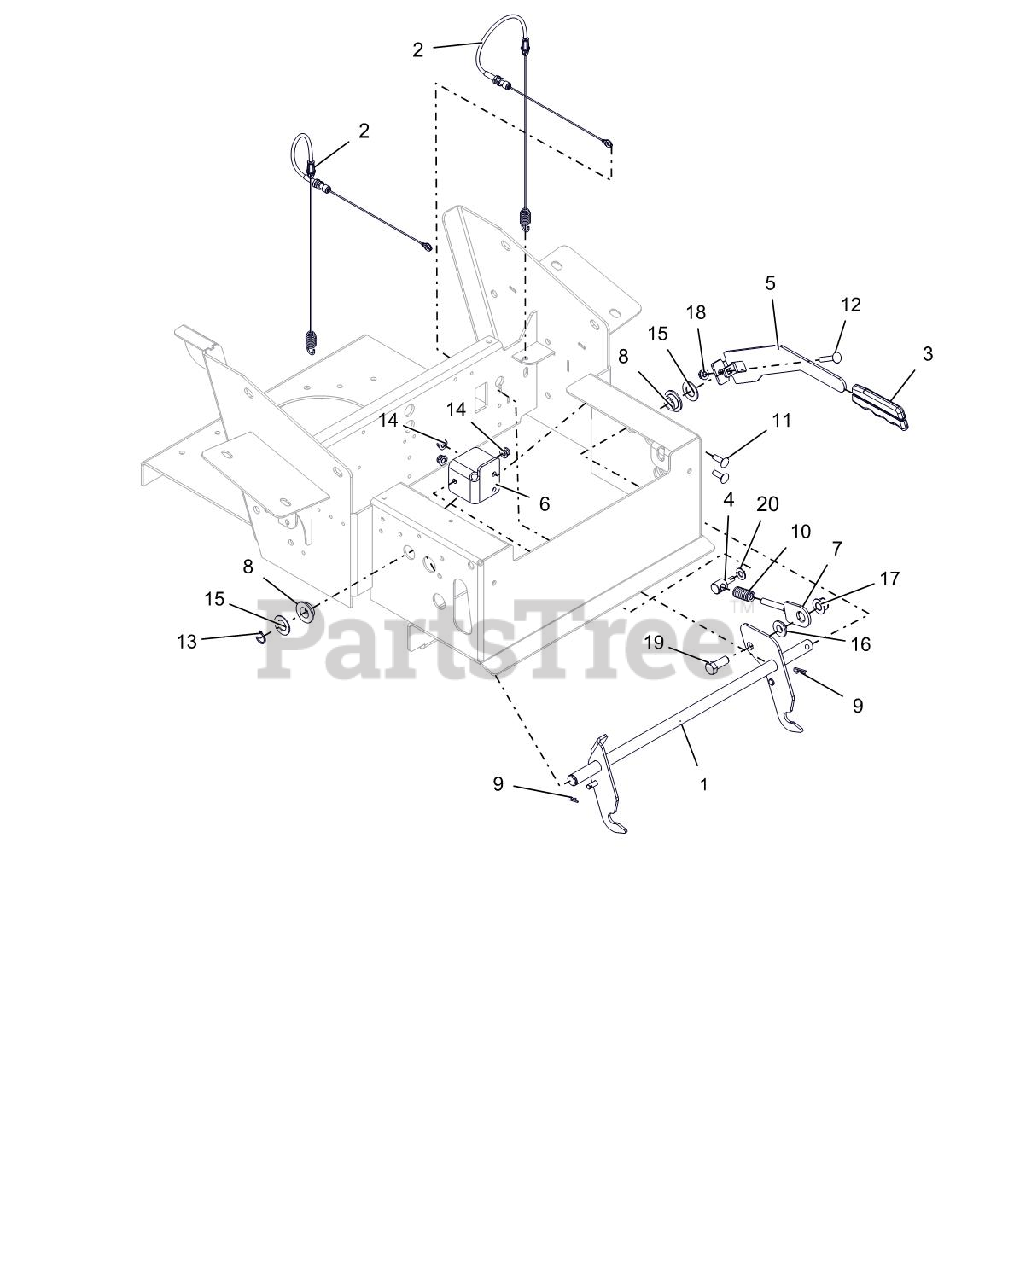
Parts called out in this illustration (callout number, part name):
1	PT/PT100 BRAKE LEVER WMT-LOW F
2	CABLE, BRAKE ACCUATING
3	GRIP, PARKING BRAKE (YELLOW)
4	.38-16 TRUNNION - LOW FILM
5	PT/PT100 BRAKE HANDLE - BLK
6	TRUNNION MTG BRACKET - BLACK
7	WLDMT, BRAKE SPRING MOUNTING
8	BSHG-FLG .762X1.48X.44 NYL
9	PIN-HAIR INT .08X.18X1.18 YWZC
10	SG-COMP .142 X .710 X 1.75
11	@BLT-RDHDSQNK .31-18X1.00 G5YZ
12	@BLT-RDHDSQNK .31-18X1.75 G5YZ
13	RG-RTNG-EXT .689X.078
14	@NUT-LK-NYL-FLG .31-18 YWZC
15	WSHR-FL-STL.755X1.375X.062YWZC
16	BSHG-FLG .515X.750X.310X1.120
17	@NUT-LK-NYL-FLG .50-13 YWZC
18	@NUT-LK-CTR-FLG .31-18 YZ GR F
19	@BLT-HEX .50-13X1.25 GR5 YWZC
20	@WSHR-FL-STL.406X.812X.065 YWZ
